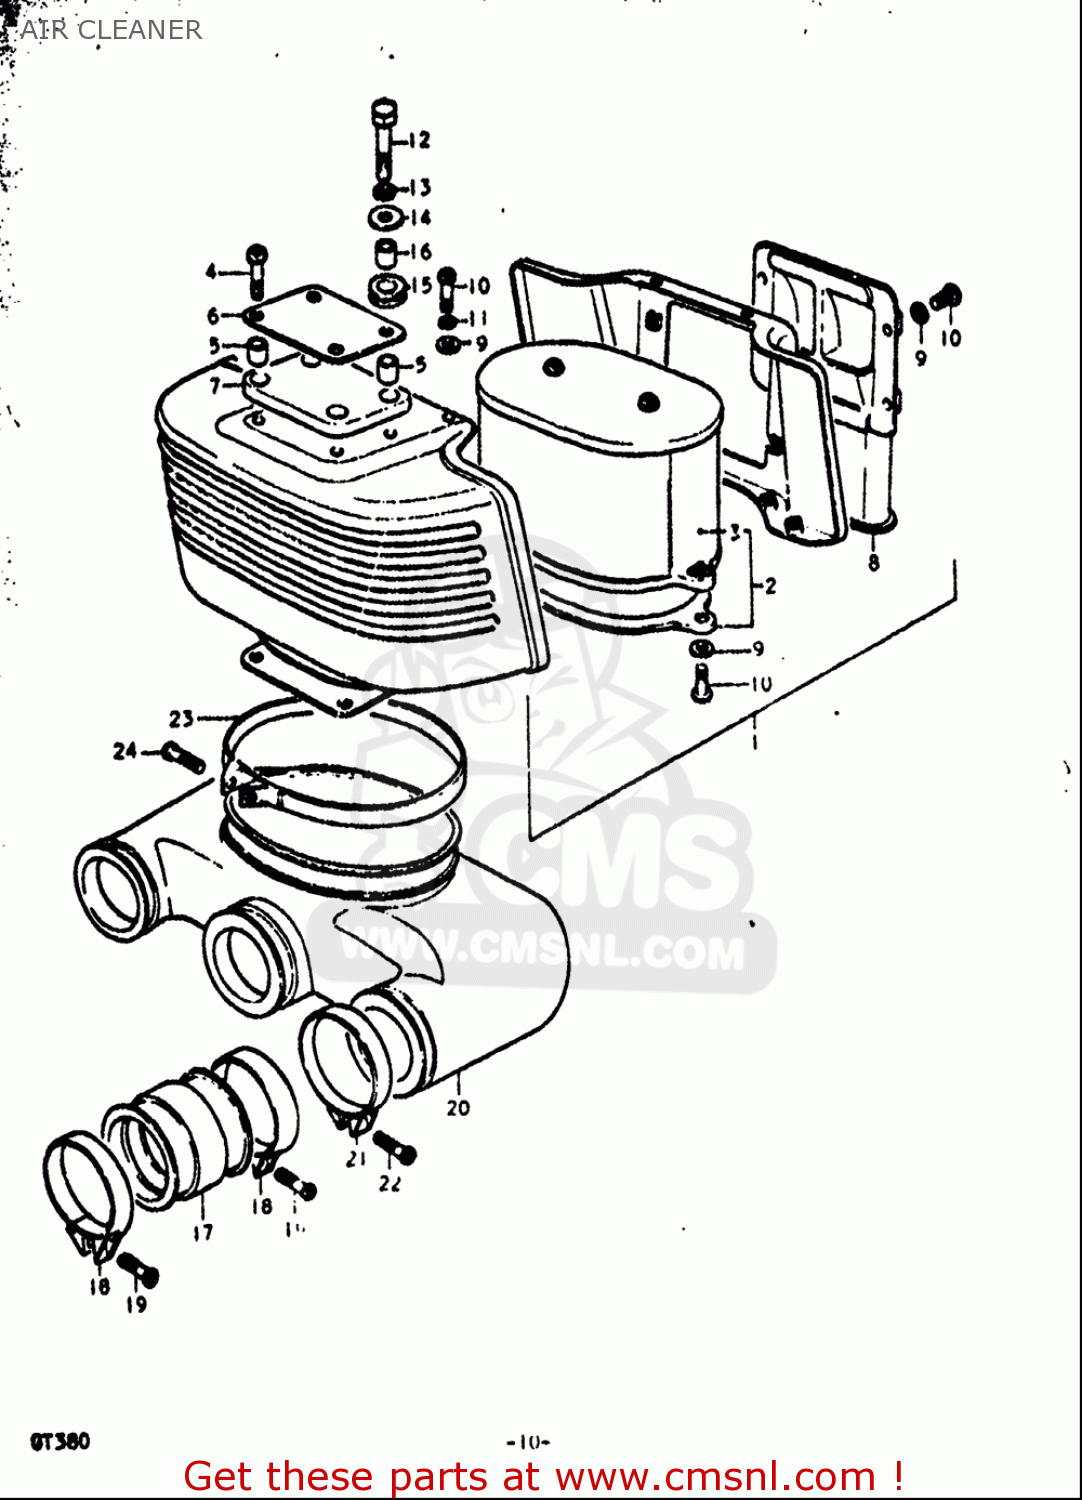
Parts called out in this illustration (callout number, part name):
4	SCREW
9	WASHER
10	SCREW
11	WASHER,LOCK
12	BOLT
13	WASHER,LOCK
14	WASHER(6.5X20X1.2)
15	CUSHION
16	SPACER,6.5X9X7
18	CLAMP
19	SCREW
22	SCREW
23	CLAMP
